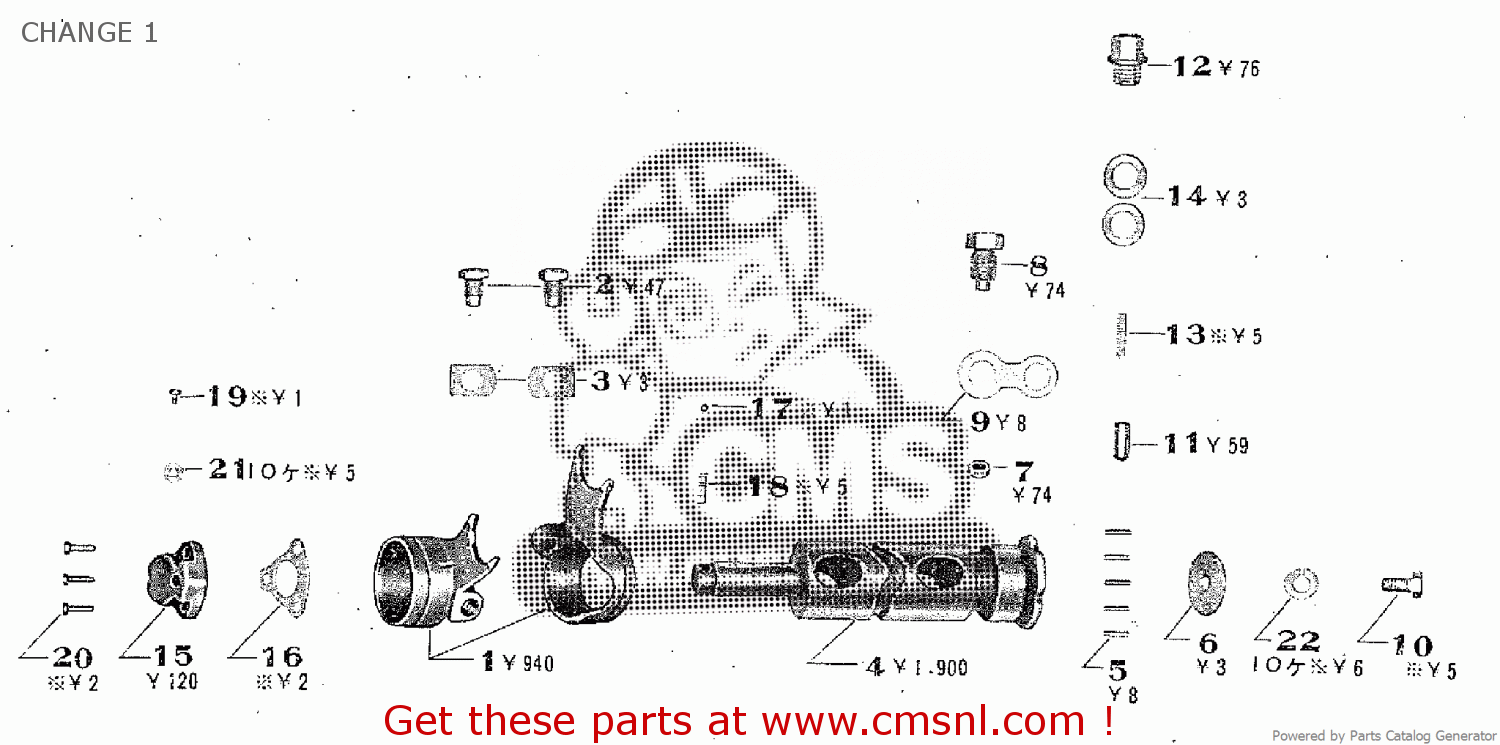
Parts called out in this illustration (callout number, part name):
1	GEAR SHIFTER
2	GEAR SHIFTER GUIDE
3	SHIFTER GUIDE SET WASHER
4	CHANGE CAM
5	CHANGE CAM PIN
6	CHANGE CAM PIN SET PLATE
7	CHANGE CAM GUIDE
8	CHANGE CAM GUIDE SET BOLT
9	CHANGE CAM GUIDE SET WASHER
10	CHANGE CAM PION SET BOLT
11	CHANGE CAM STOPPER
12	CHANGE CAM STOPPER HOLDER
13	CHANGE CAM STOPPER SPRING
14	CHANGE CAM STOPPER ADJUSTER WASHER
15	NEUTRAL SWITCH BODY
16	NEUTRAL SWITCH PACKING
17	NEUTRAL SWITCH BALL
18	NEUTRAL SWITCH BALL SPRING
19	4X6 CROSS SCREW
20	5X15 CROSS SCREW
21	4MM PLANE WASHER
22	8MM SPRING WASHER
